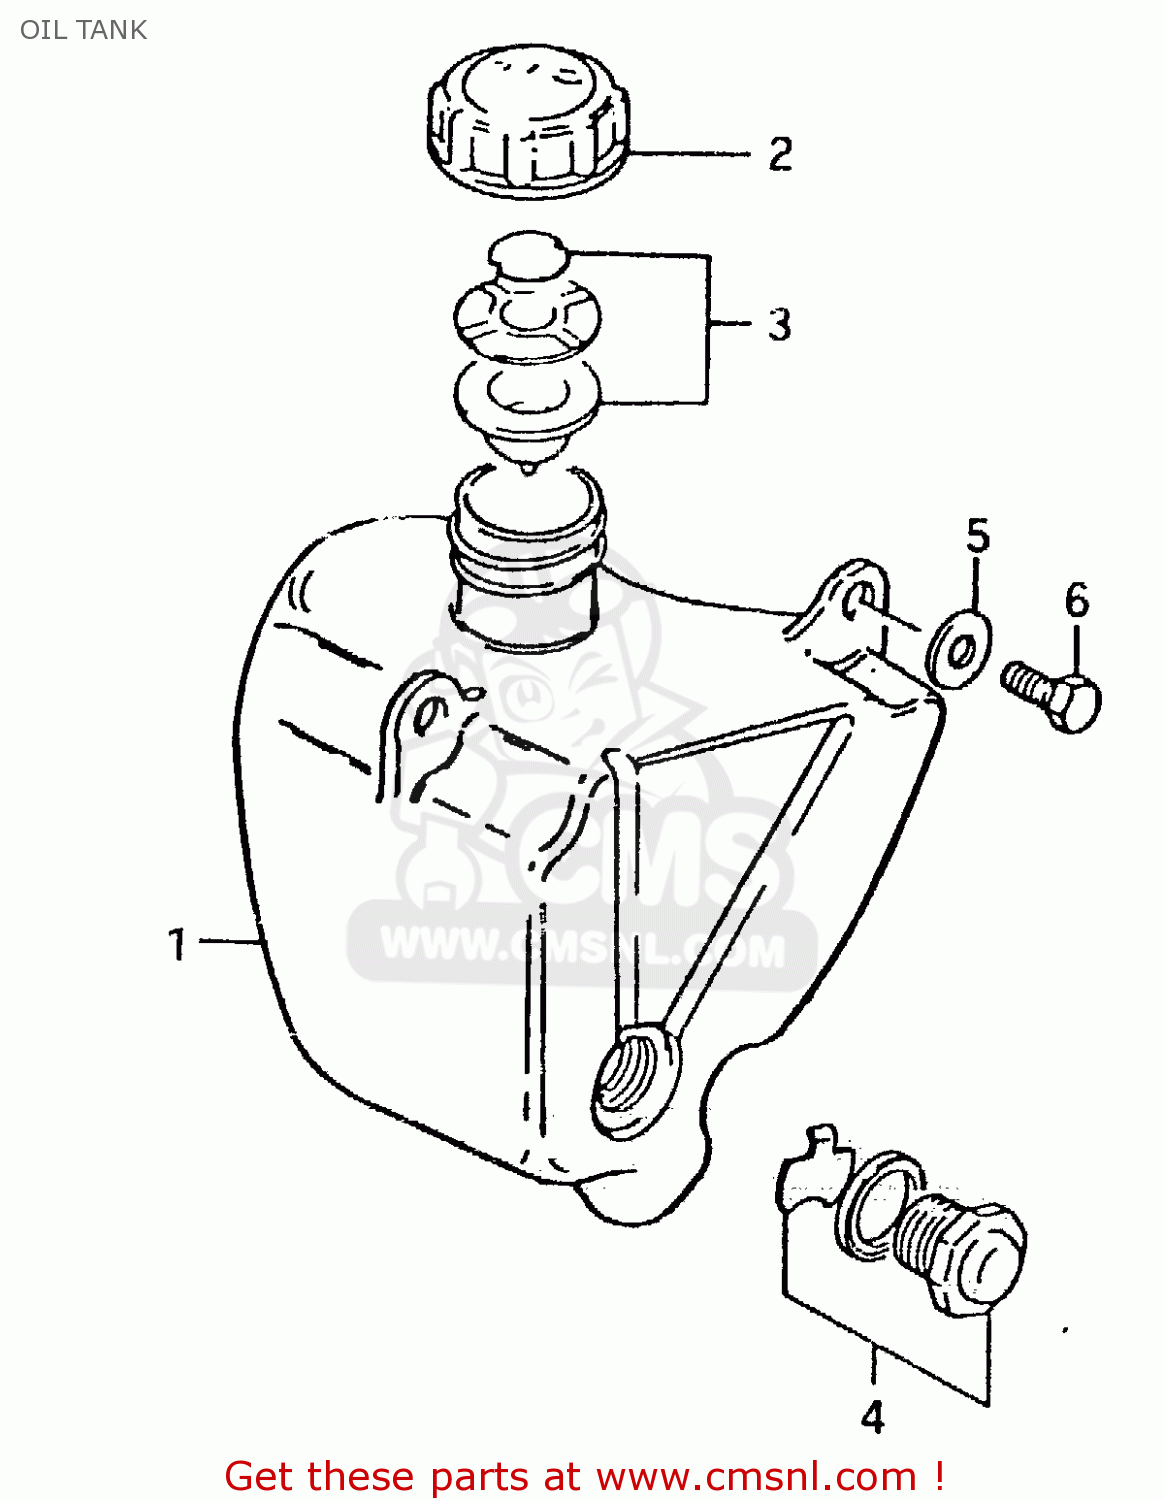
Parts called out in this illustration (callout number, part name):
1	TANK,OIL
2	CAP,OIL TANK
3	GASKET SET (NAS)
4	LENS SET,OIL LEVEL
5	WASHER
6	BOLT, UPPER
